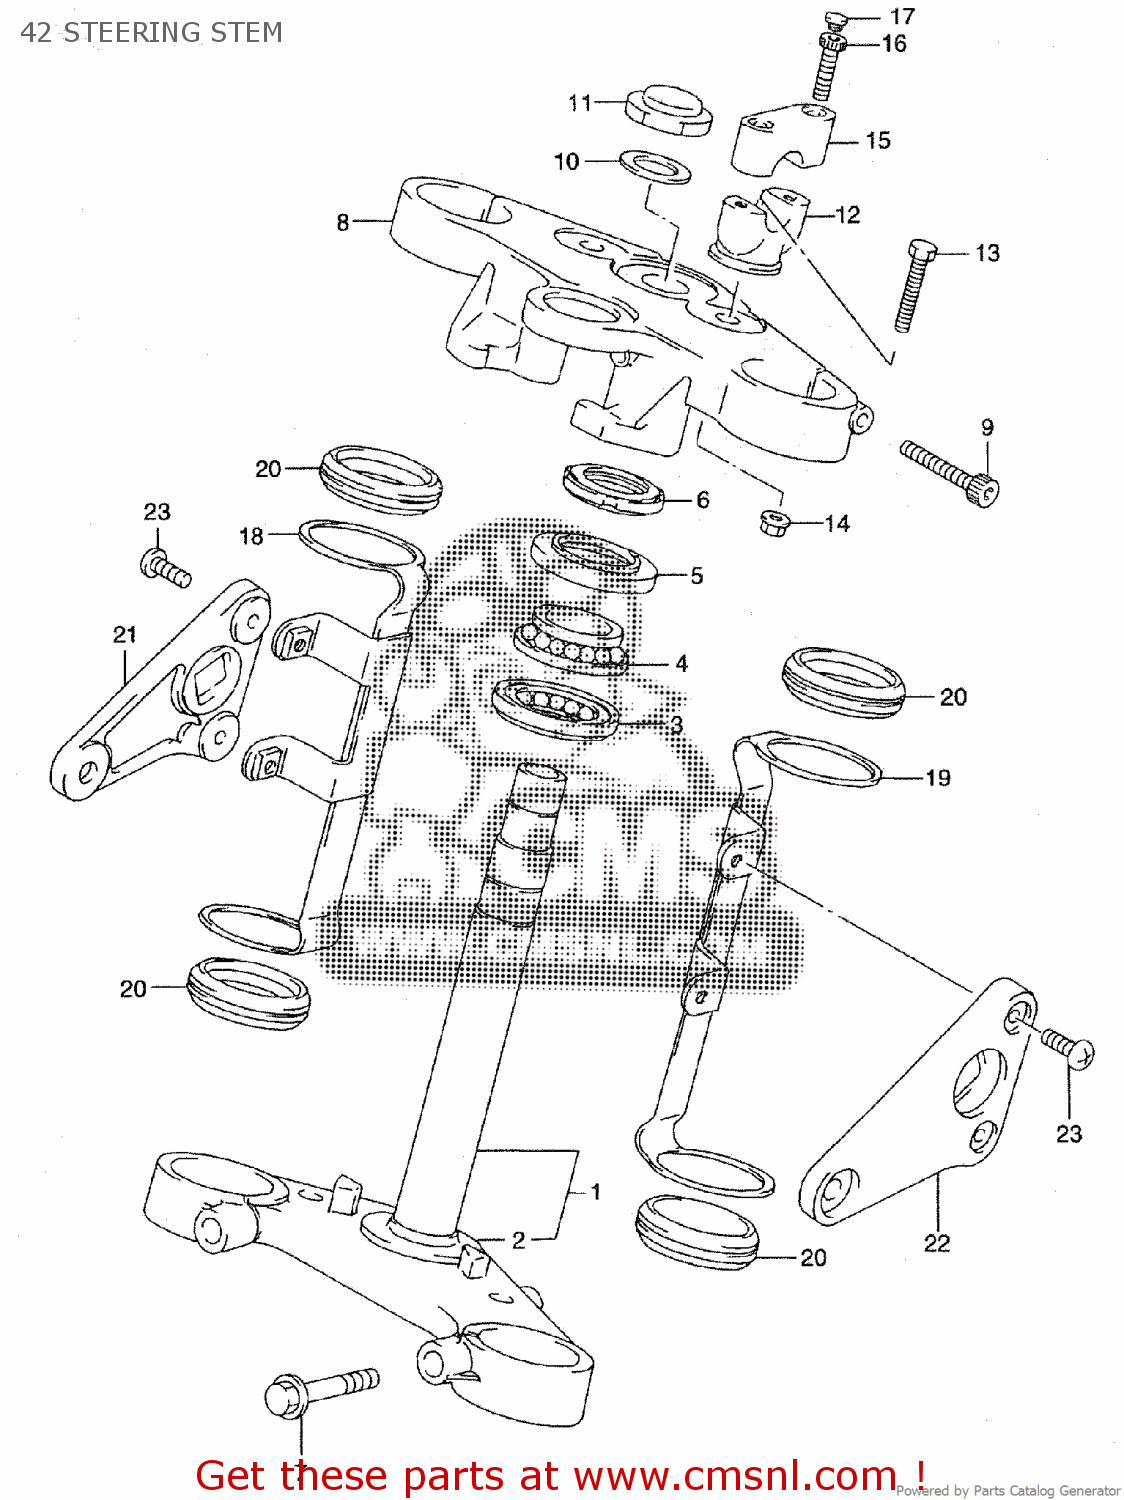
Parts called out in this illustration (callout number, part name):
2	SEAL,STEERING LWR
3	BEARING(30X55X17)
4	BEARING(25X47X15)
5	DUST SEAL,STEERING UPR
6	NUT,STEERING STEM(25X44X10)
7	BOLT
9	BOLT
10	WASHER(22.5X35.9X1.6)
11	NUT,CAP
12	HOLDER,HANDLE LWR
14	NUT
15	HOLDER,HANDLE UPR
16	BOLT
17	CAP(OD:11)
18	BRACKET,HEADLAMP HOUSING,R
19	BRACKET,HEADLAMP HOUSING,L
20	DAMPER,HEADLAMP HSG BRACKET
21	STAY,HEADLAMP HOUSING,R
23	SCREW(6X20)
